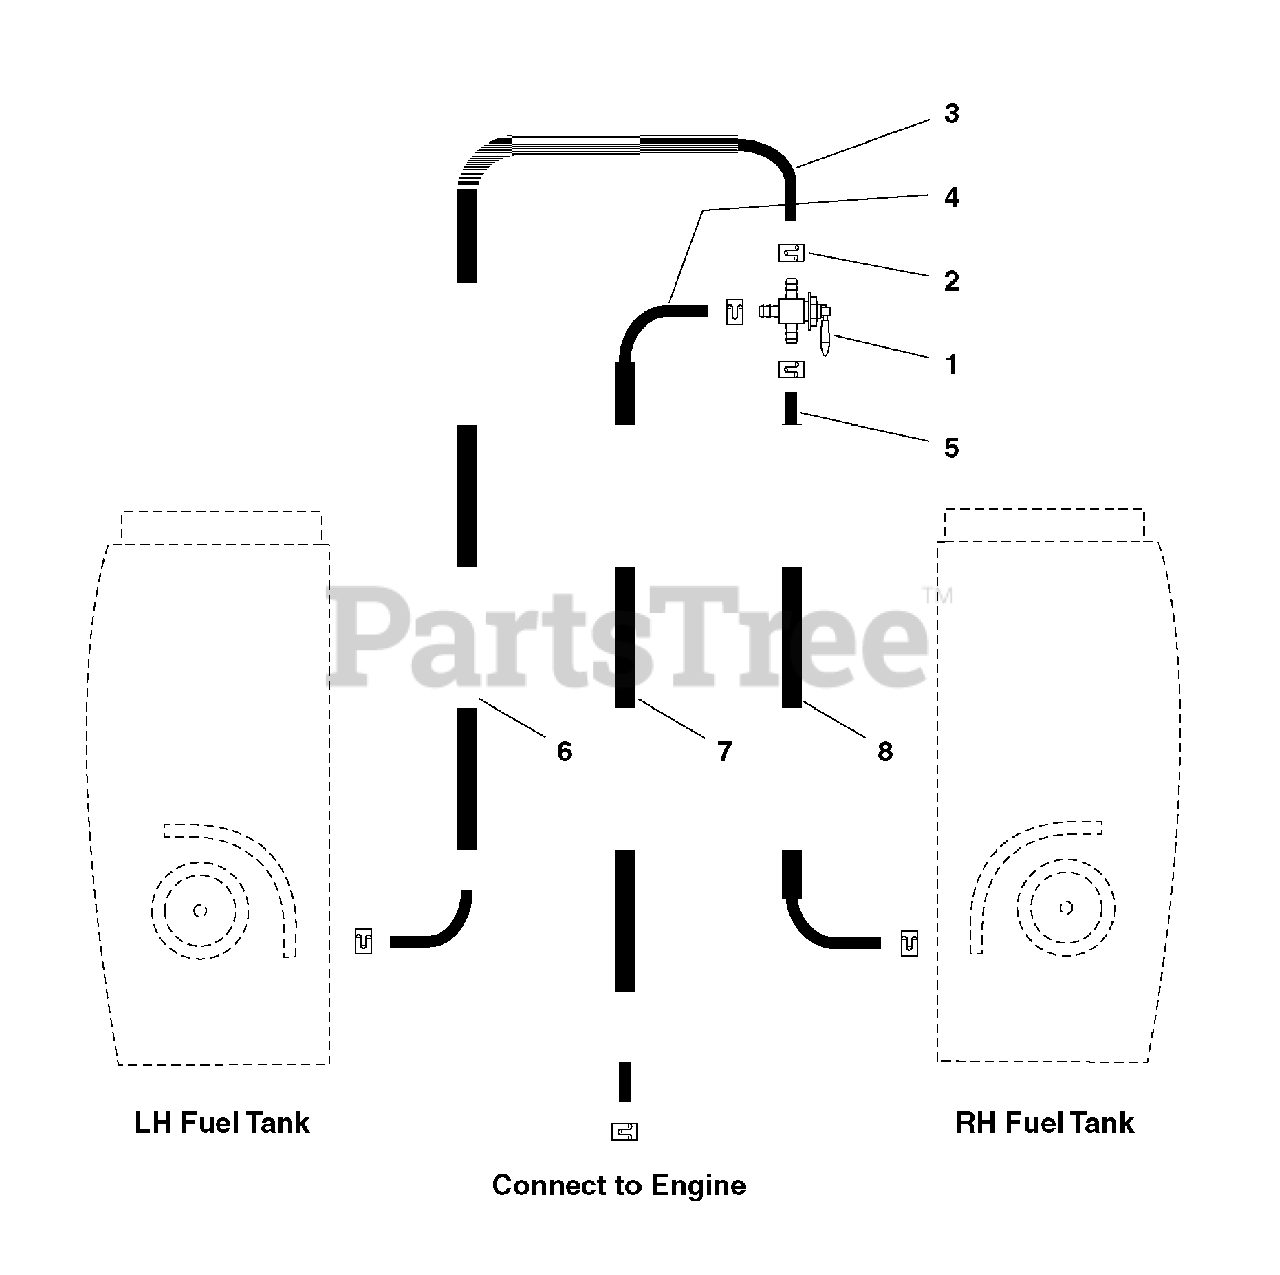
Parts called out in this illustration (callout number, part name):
1	VALVE, Fuel Shut Off
2	CLAMP, Hose
6	WIRE LOOM, 54"
7	WIRE LOOM, 49"
8	WIRE LOOM, 35"
